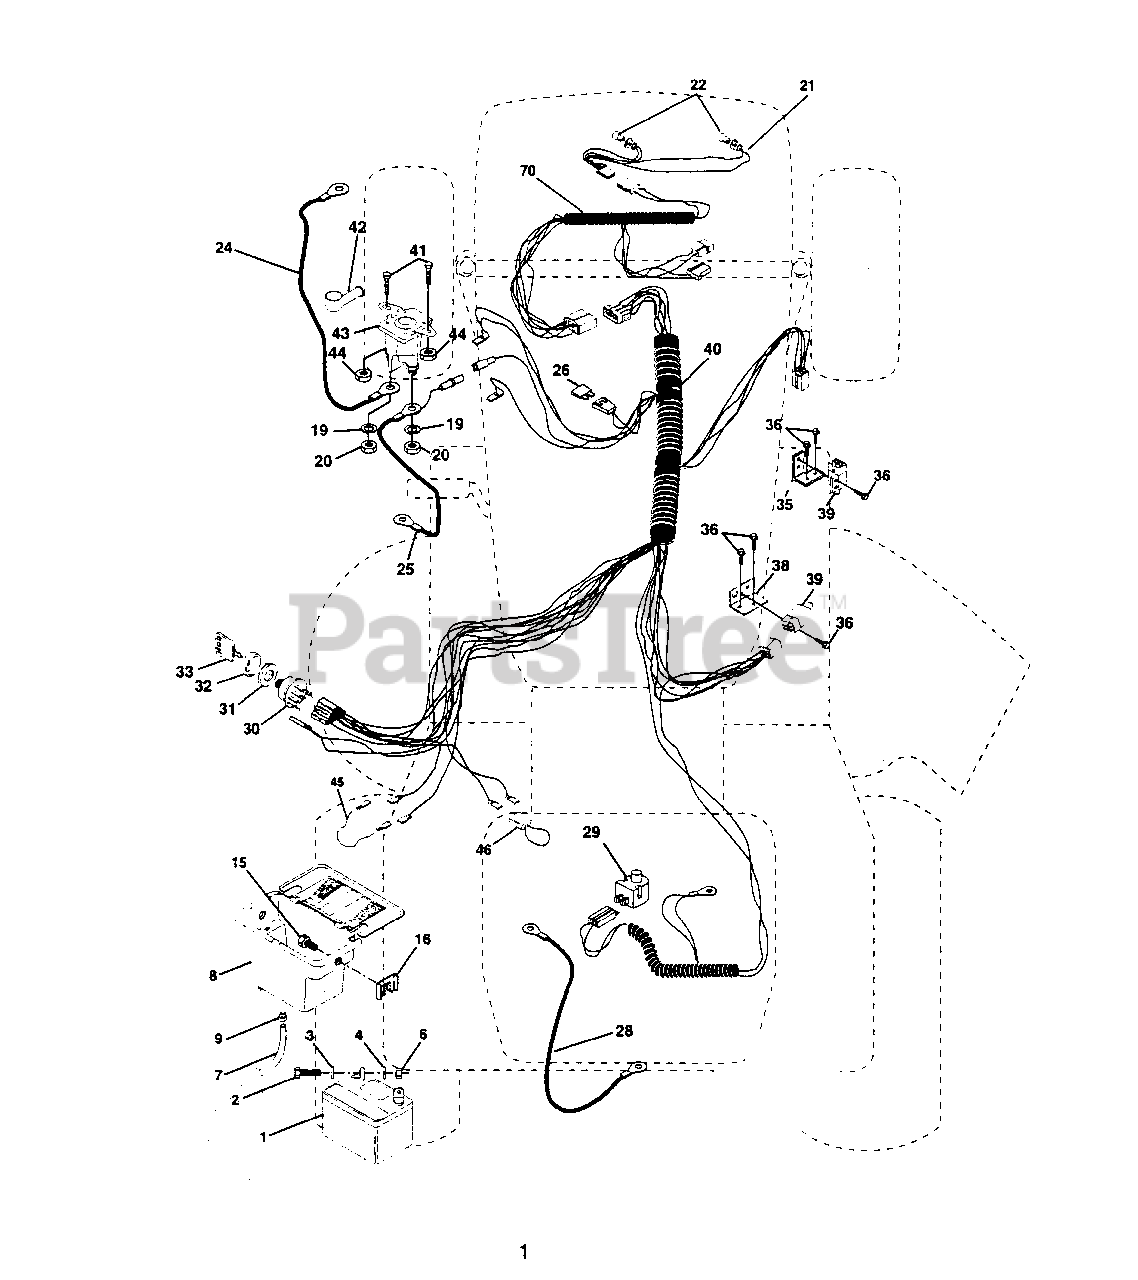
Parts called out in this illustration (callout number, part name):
1	Battery 12 Volt 25 AMP
2	Bolt Hex Hd 1/4-20unc X 3/4
3	Washer 9/32 X 5/8 X 16 Ga.
4	Washer Lock Hvy Helical 1/4
5	Caps Battery 20/25/30 AMP
6	Nut Fin Hex 1/4-20 Unc
7	Tube Plastic 12"
8	Case Battery
9	Clamp Hose Olive
15	Screw Cap Hex Nylon 3/8-16 x 1
16	Nut, Nylon 3/8-16
19	Washer Lock 1/4
20	Nut Jam Hex 1/4-20 Unc
21	Harness Asm Light W/4152j
22	Bulb Light #1156
23	Washer Lock Internal Tooth 1/4
24	Cable Battery 6 Ga 11" red
25	Cable Battery 6 Ga 44" red
26	Fuse 30 AMP Auto Green
28	Cable Ground 6 Ga 12" black
29	Switch Plunger Nc Gray
30	Switch Ign 4 pos w/lights
32	Cover Sw Ignition
33	Key Ign Modleded Generic
35	Bracket Switch Clutch
36	Screw Tap Hex #10-24unc X 1/2
38	Bracket, Switch, Interlock
39	Switch Intlk Clutch Red 4 Term
40	Harness Chassis LT PL Mech
41	Bolt Blk Fin Hex 1/4 - 20 x 3/4
42	Cover Terminal Red
43	Solenoid
44	Nut Keps Hex 1/4-20 Unc
45	Adapter Ammeter Rectangular
46	Protection Wire Loop
70	Harness, Eng.
